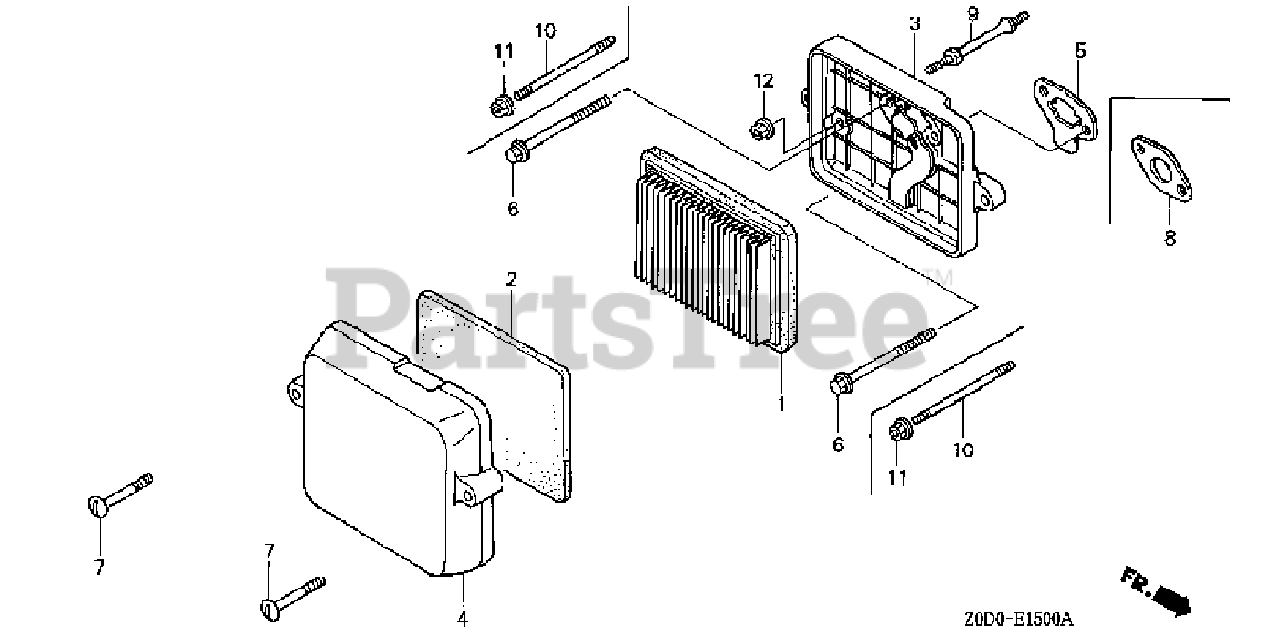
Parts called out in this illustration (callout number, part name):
1	ELEMENT, AIR CLEANER
2	FILTER (OUTER)
3	HOUSING, AIR CLEANER
4	COVER, AIR CLEANER
5	GASKET, AIR IN. JOINT
6	BOLT (5X77) (CT200)
7	BOLT, AIR CLEANER COVER
